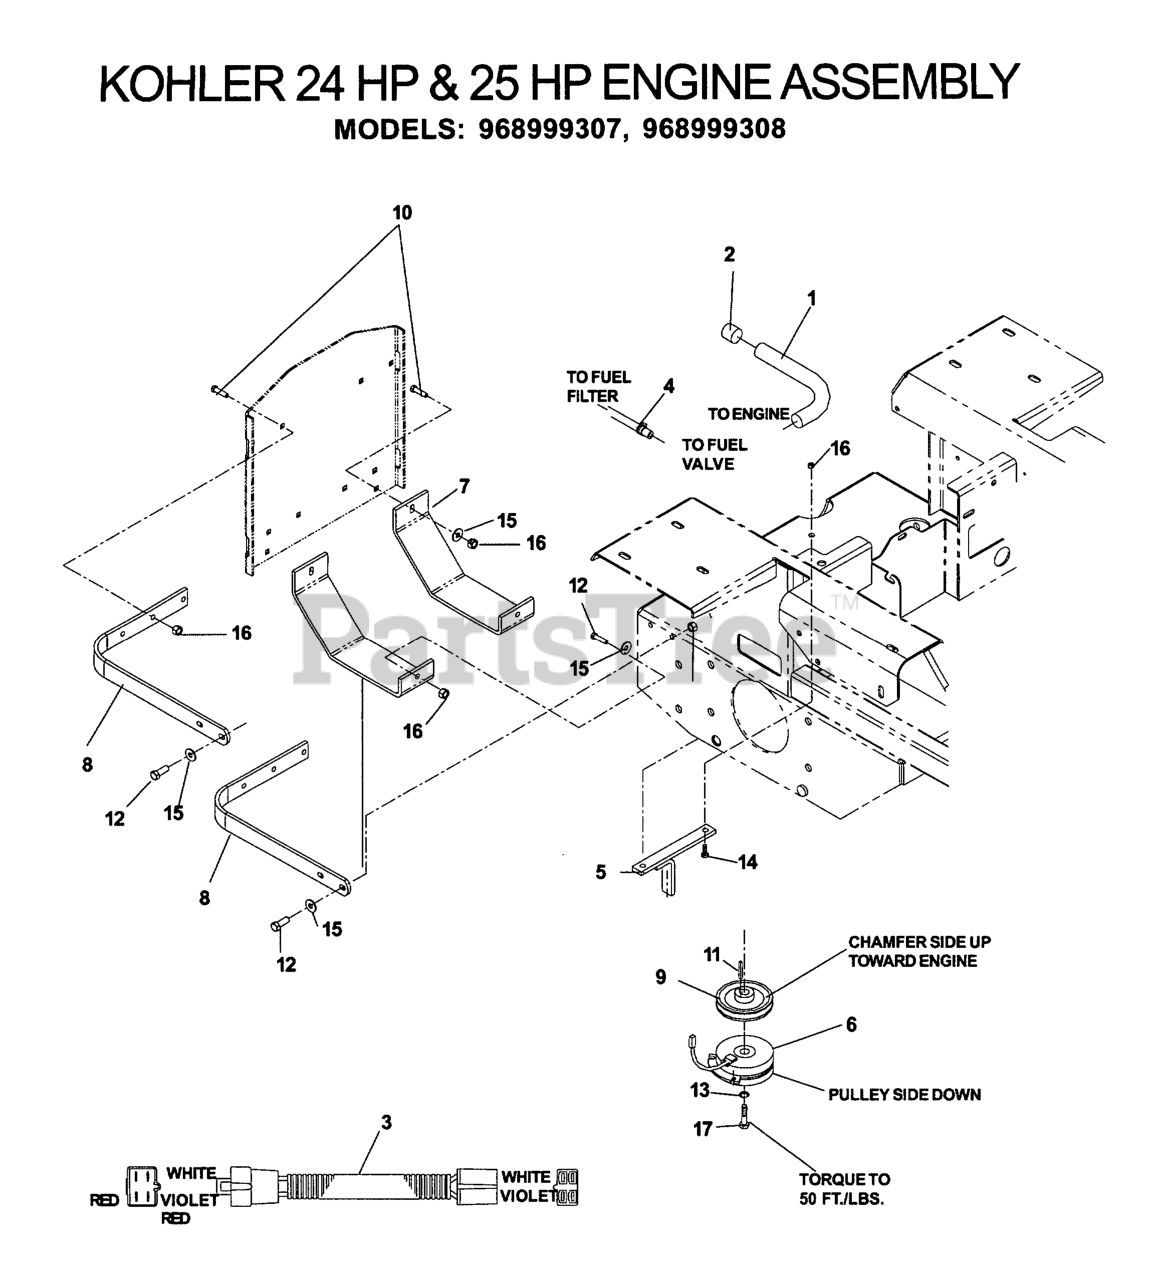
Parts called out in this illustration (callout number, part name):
1	OIL DRAIN HOSE
3	KOH PIGTAIL
4	FUEL LINE 13"
5	CLUTCH TIE DOWN
6	ELECTRIC CLUTCH W/CABLE
7	SKID PLATE
8	ENGINE SHROUD BRKT
10	RHSSNB 5/16C X 1.0
11	KEY, 1/4 SQ X 1 1/4
12	HCS 5/16C X 1
13	WASHER 7/16 LOCK
14	HCS 5/16C X 1 3/4
15	WASHER 5/16 FLAT
16	NUT 5/16 NYLOC
17	BOLT 7/16F X 2 1/2
